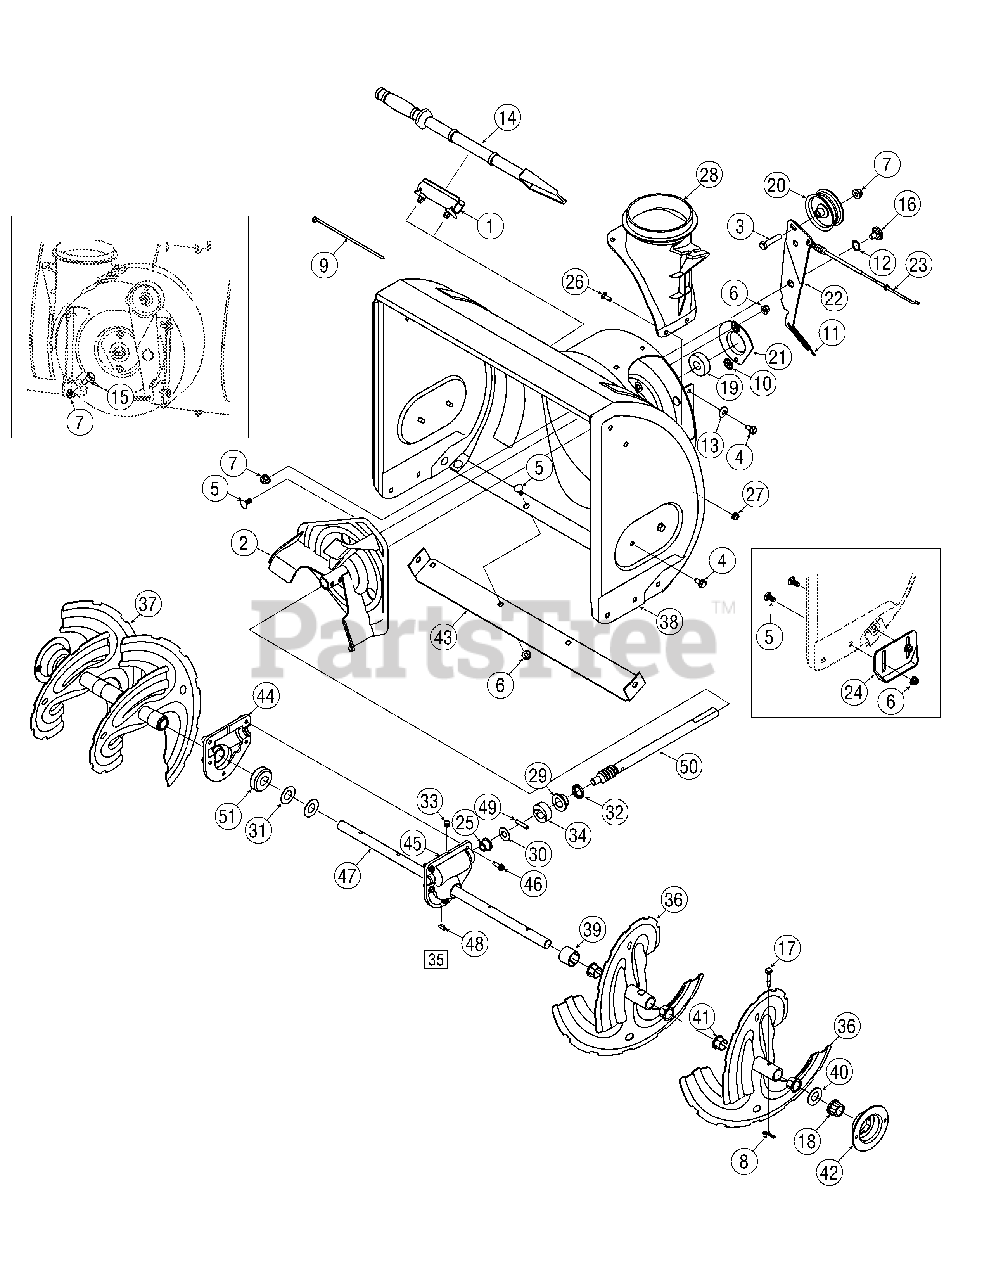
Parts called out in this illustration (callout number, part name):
1	Clean Out Tool Mount
2	Impeller Assembly, 12"
3	Hex Screw, 3/8-16 x 1.75
4	Hex Washer Screw, 5/16-18 x .750
5	Carriage Bolt, 5/16-18 x .750
5	Carriage Bolt, 5/16-18 x 1.00
6	Flange Lock Nut, 5/16-18
7	Flange Lock Nut, 3/8-16
8	Bow-Tie Cotter Pin
9	Cable Tie, 3/16 x .05 x 7.4
10	Push Nut, .25 Dia.
11	Extension Spring
12	Wave Washer, .625 x .885 x .015
13	Bell Washer, .340 x .872 x .060
14	Chute Cleanout Tool
15	Shoulder Bolt, .496 x .336 x 3/8-16
16	Shoulder Screw, .625 x .17 x 3/8-16
17	Shear Pin, .25 x 1.50
18	Hex Flange Bearing, .75 ID
19	Ball Bearing, .75 ID x 1.85 OD
20	Idler Pulley, 2.75 OD
21	Bearing Housing, 1.85 ID
22	Auger Idler Bracket
23	Auger Drive Cable
24	Skid Shoe, Standard
24	Standard Polymer Reversible Shoe Kit
25	Flange Bearing, .50 ID x .75 OD x .59
26	Carriage Screw, 1/4-20 x .75
27	Flange Lock Nut, 1/4-20
28	Chute Adapter, 5"
29	Flange Bearing, .75 ID x 1.0 OD x .59
30	Flat Washer, .51 x 1.12 x .06
31	Flat Washer, .760 ID x 1.50 ID
32	Oil Seal, .75 x 1.131 x .188
33	Plug, 1/4 x .437
34	Thrust Collar, .756 ID x .600
35	Gearbox Assembly, 22"
36	Spiral Assembly, LH
37	Spiral Assembly, RH
38	Auger Housing Assembly, 22"
39	Spacer, 1.2500 x .75 ID x 1.00
40	Flat Washer, .76 x 1.49 x .06
41	Flange Bushing, .800 ID x .910 OD
42	Bearing Housing, 1"
43	Shave Plate, 22"
44	Housing Assembly, RH
45	Housing Assembly, LH
46	Hex Washer Screw, 1/4-20 x .750
47	Auger Axle, 22"
48	Hi-Pro Key
49	Dowel Pin, .25 OD x 1.25 LG
50	Worm Shaft, .75 OD
51	Worm Gear 20 T
